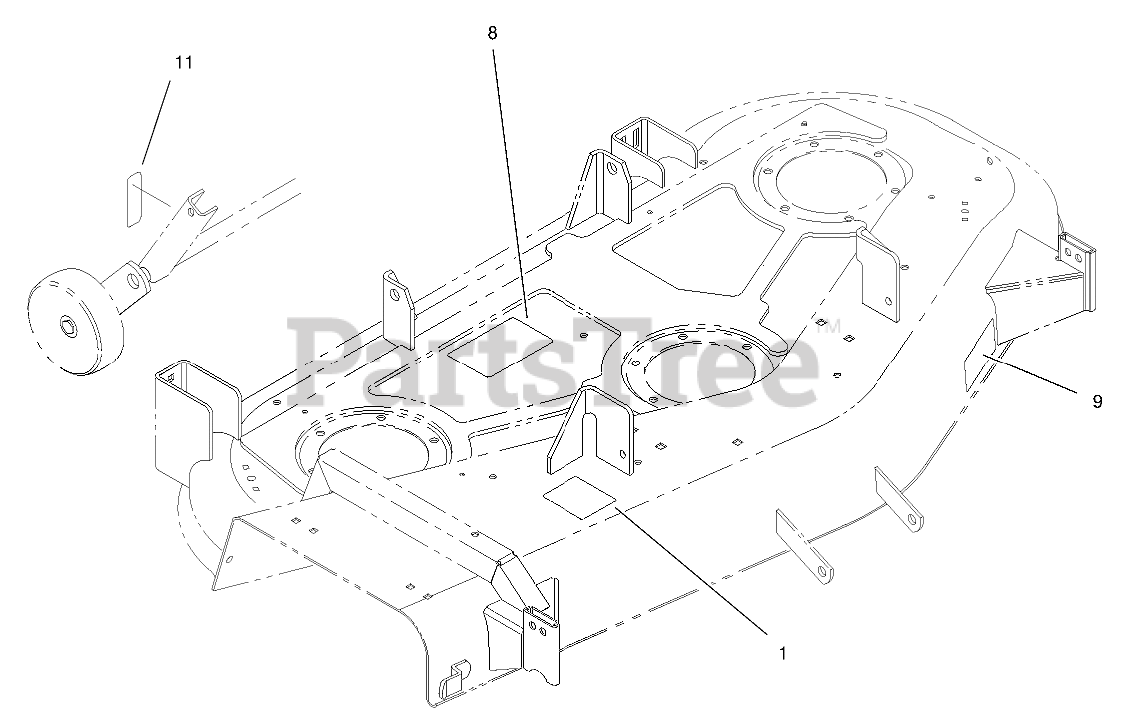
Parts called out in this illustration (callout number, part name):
1	DECAL-BELT ROUTING
8	DECAL-BELT ROUTING
9	DECAL-ADJUSTMENT, WHEEL
11	Decal-HOC (only on: 78370)
